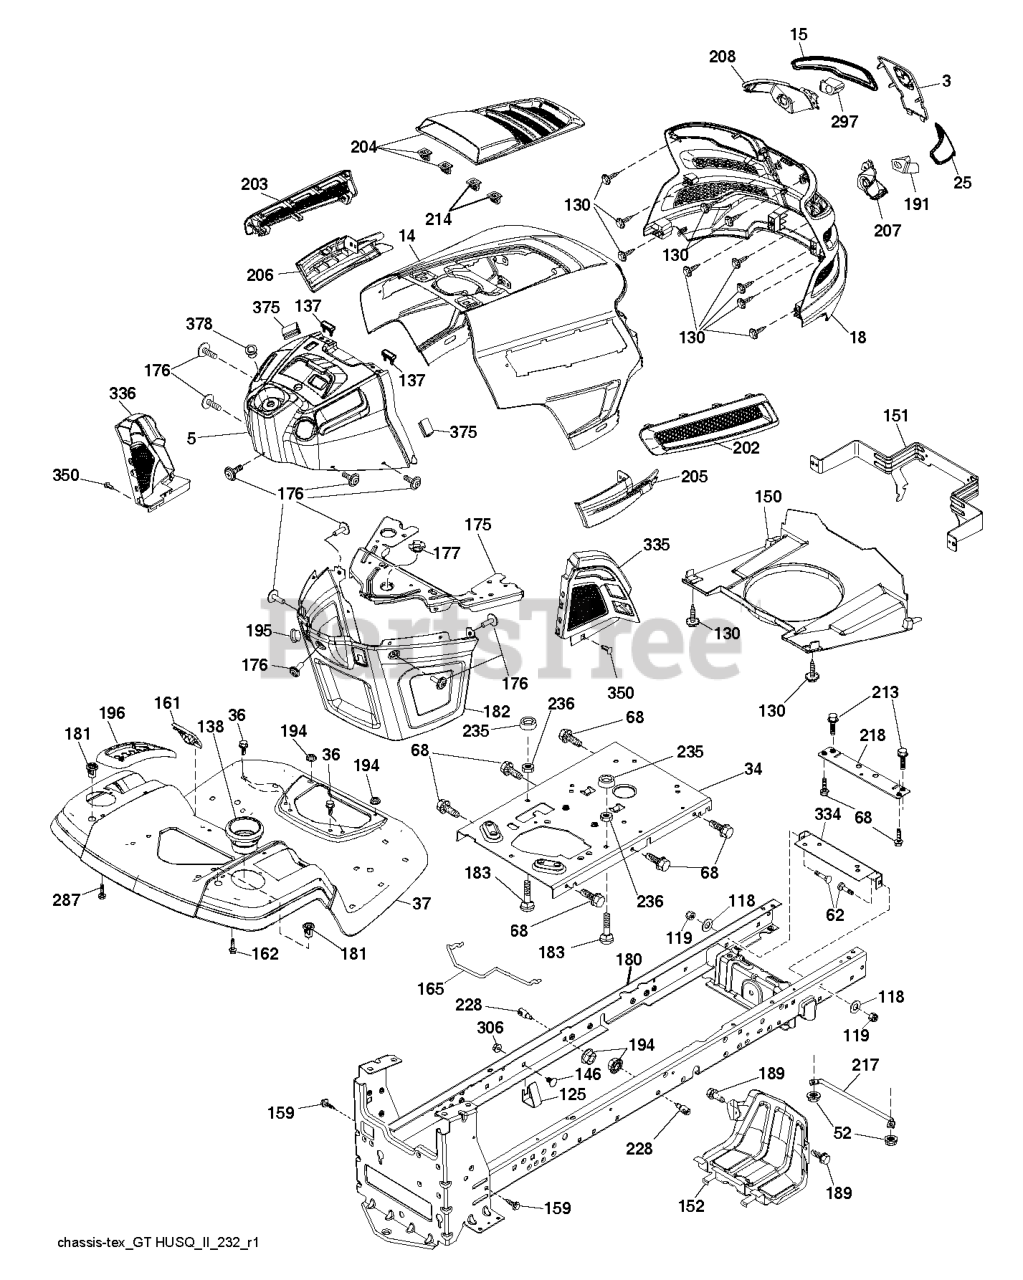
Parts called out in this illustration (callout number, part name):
3	APPLIQUE.SUBASM.GT.HUSQ.II
5	DASHBOARD.UPPER.ASM.GT2.X498
14	HOOD.ASM.HUSQVARNA.GT.TEX.ORAN
15	LENS.HEADLIGHT.LH.GTII.2011
18	GRILLE SUBASM.GT.II.LOW.HDLGHT
25	LENS.HEADLIGHT.RH.GTII.2011
34	PLATE.ENGINE.WELDED.CHASSIS
36	SCREW 5/16"
37	FENDER.TLT.FS.W/CPH/FW/RSF.668
118	WASHER
125	CLIP.FUEL.LINE
137	BUMPER DASH
138	HOLDER.CUP.LT.GREY
146	BOLT.RDHD.SHT.SQNK.3/8-16X5/8
150	AIR.DUCT.GTV2(2.54"RING HEIGHT
151	BRACKET.PIVOT.HOOD.GT.HUSQ.II
152	SHIELD.BROWNING.PNT.GT.V2
159	SCREW, 3/8-16X3/4
161	WINDOW.FUEL.LT.HUSQ.TEX.498
165	SUPPORT.TANK.REAR.W/TEX
175	PLATE.PNT.CROSSMEMBER.HUSQ/PRE
176	SCREW.#10-24X5/8.RN.QU
177	BUSHING STEERING
180	CHASSIS
181	BUSHING.MNT.FEND.CRGO.TEX.49
182	DASH LOWER.HUSQ.PRED NO CRUISE
189	SCREW
191	INSERT.REFLECTIVE.RH.HUSQ.GTII
195	PLUG.HOLE.DASH.LOWER.12V.BLK
196	DECKLFT.CONSOL FULL ASSM GREY
202	VENT.SIDE.RH.GT.HUSQ.II.
203	VENT.SIDE.LH.GT.HUSQ.II.498
204	VENT.TOP.ASM.HUSQ.GT2
205	SIDE.TRIM.RH.GT.HUSQ.II
206	SIDE.TRIM.LH.GT.HUSQ.II.GRAY
207	HEADLIGHT.CUP.BEZEL.HUS.GT2.RH
208	HEADLIGHT.CUP.BEZEL.HUS.GT2.LH
213	SCREW HEXAGON HEAD SCREW 5/16-
214	CLIP.RETAINER.TINNER.
217	ROD.PIVOT.HOOD
218	X-PIECE.HOOD.STOP.NON/
228	STUD.W/"D"ANTI-ROTATION
236	NUT.CENTERLOCK.5/16-
287	SCREW 1/4X20
297	INSERT.REFLECTIVE.LH.HUSQ.GTII
306	NUT LOCK FLG 3/8-16 UNC
334	BRACKET.ENGINE
335	COVER.LOWER.DASH.RH.BLACK
336	COVER-LH.LOWER.DASH.GT2.BLACK
350	CLIP.X-MAS.TREE
375	BUMPER CLIP-ON. DASH 1"
378	BUSHING FLANGE; PLASTIC
